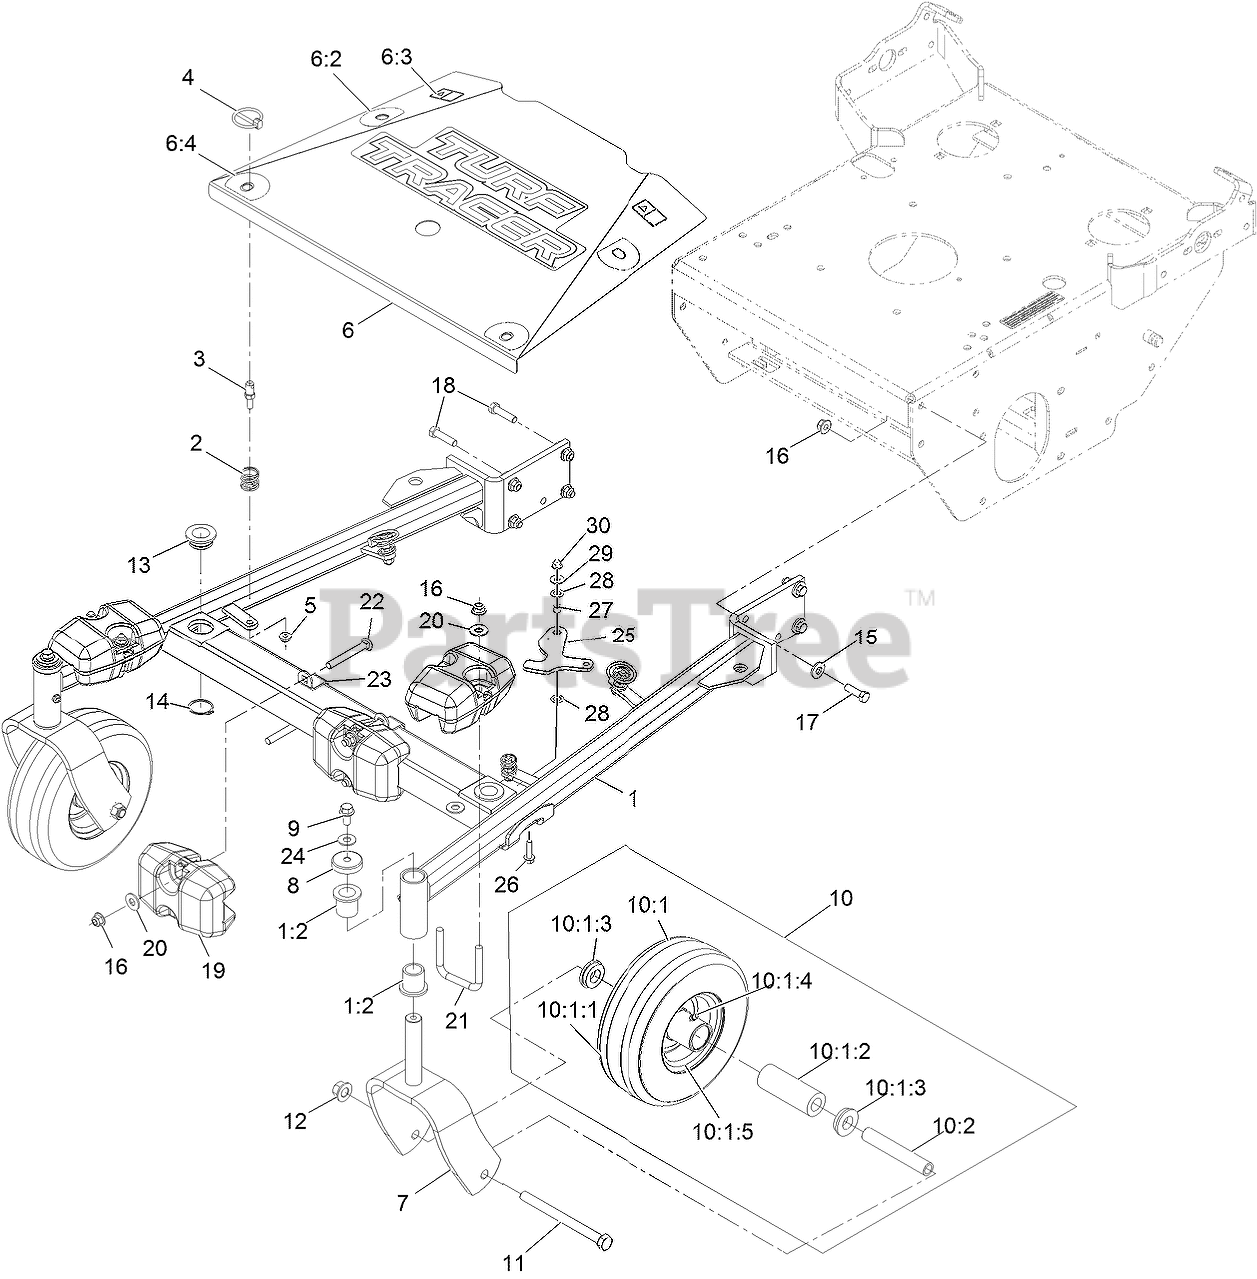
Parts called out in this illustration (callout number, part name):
1	ASM, FRAME W/ BUSHINGS, 4
1:2	BEARING-FLANGED
3	PIN, SPRING
4	PIN-LYNCH
5	NUT-HF, NI
6	ASM, SHIELD W/ DECALS, 48
6:2	DECAL-TURF TRACER
6:3	DECAL-WARNING
6:4	DECAL-SCRATCH COVER
7	FORK, CASTER
8	CAP, DUST
9	SCREW-HHF
10	KIT, SP CASTER WHEEL REPL
10:1	Wheel And Tire ASM
10:1:1	Tire
10:1:2	BEARING
10:1:3	BUSHING
10:1:4	FITTING-GREASE
10:1:5	Wheel
11	SCREW-HH
12	Nut-Lock 1/2-13
13	BUSHING-DECK
14	RING-RETAINING
15	WASHER-BELLEVILLE
16	NUT-HF, NI
17	SCREW-HH
18	SCREW-HH
19	WEIGHT-SUPPORT, CASTER
20	WASHER-FLAT
22	SCREW-CARR
23	STRAP, WEIGHT
25	LATCH, DECK HEIGHT
26	Screw-HHF
27	Spacer-Grommet
28	WASHER-CONICAL
29	WASHER-FLAT
30	NUT-HF, NI
